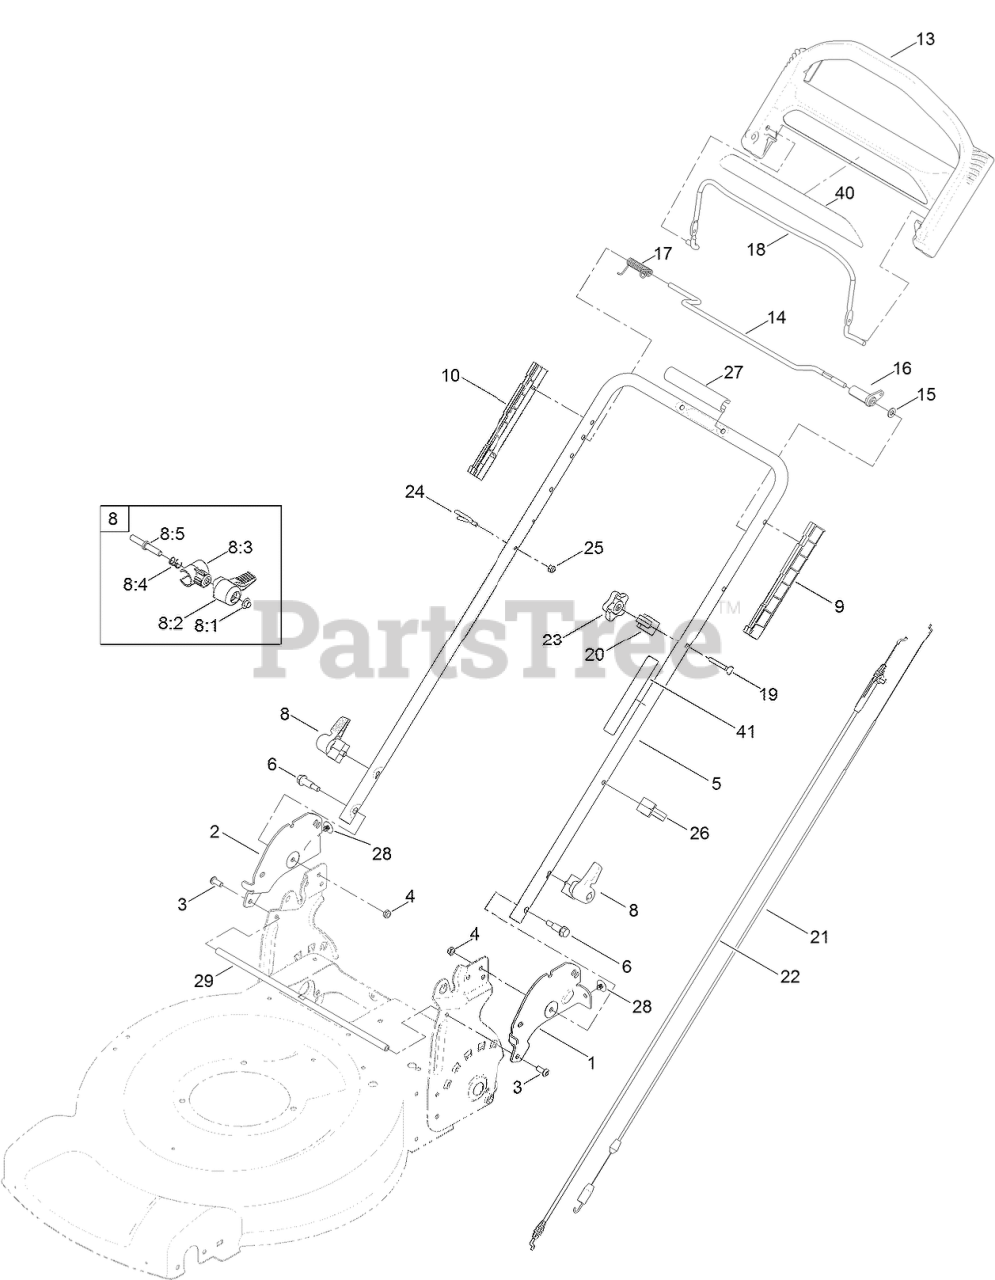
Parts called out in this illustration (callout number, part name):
1	PLATE-HANDLE, LH
2	PLATE-HANDLE, RH
3	SCREW-HSBH
4	NUT-LOCK, NI
6	BOLT-SHOULDER
8	QUICK RELEASE ASM
8:1	NUT-PUSH
8:2	LEVER
8:3	ANCHOR-SPRING
8:4	SPRING-COMPRESSION
8:5	ROD-RELEASE
9	GUIDE-LH
10	GUIDE-RH
13	HANDLE-CONTROL
14	BAR-CONTROL, TRACTION
15	WASHER-PLAIN
16	LEVER-TRACTION
17	Spring-Torsion
18	BAIL-BRAKE
19	SCREW
20	ANCHOR-CABLE
21	CABLE-TRACTION
22	CABLE-BRAKE
23	KNOB-HANDLE, LOCKING
24	GUIDE-ROPE
25	NUT-LOCK, NI
26	GUIDE-CABLE
27	HANDLE-COVER
28	CLIP-TREE
29	Rod-Stiffener
41	DECAL-TRACTION, ADJUST
